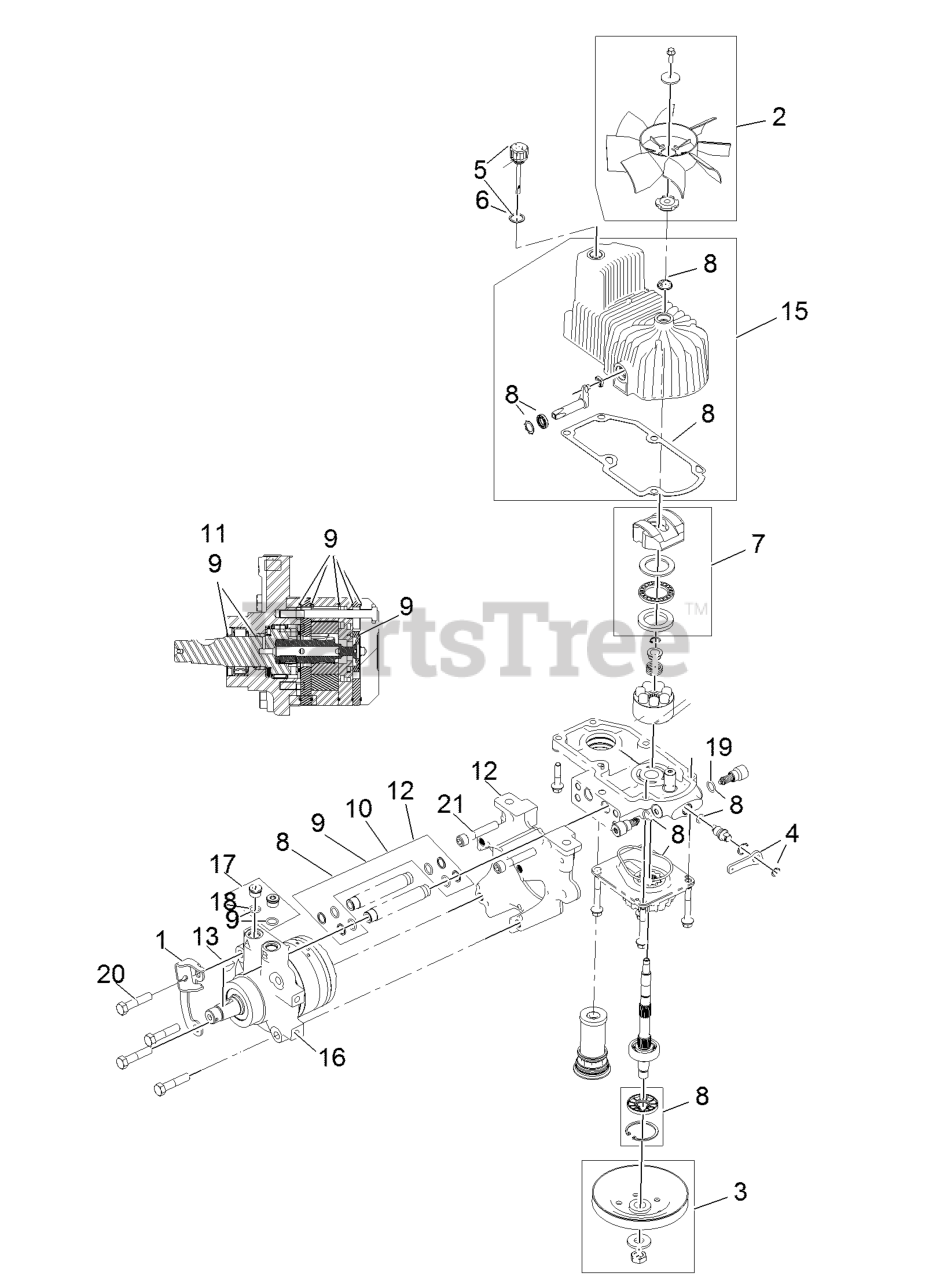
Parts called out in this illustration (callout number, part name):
1	BRACKET-ANCHOR, CABLE
2	FAN KIT
3	PULLEY KIT
4	HANDLE-BYPASS VALVE, HYDRO
5	DIPSTICK-HYDRO W/GASKET
6	GASKET-DIPSTICK, HYDRO
7	SWASH BLOCK KIT
8	PUMP SEAL KIT
9	MOTOR SEAL KIT
10	TUBE SEAL KIT
11	OUTPUT SHAFT SEAL KIT
12	NOSE CUP-UHT
13	KEY-WOODRUFF
15	HOUSING-HYDRO, RH
16	MOTOR-HYDRAULIC RH 240CC
17	MAGNETIC PLUGS SERVICE KIT
19	O-RING-CHECK VALVE
20	SCREW HH
21	SCREW-HSH
